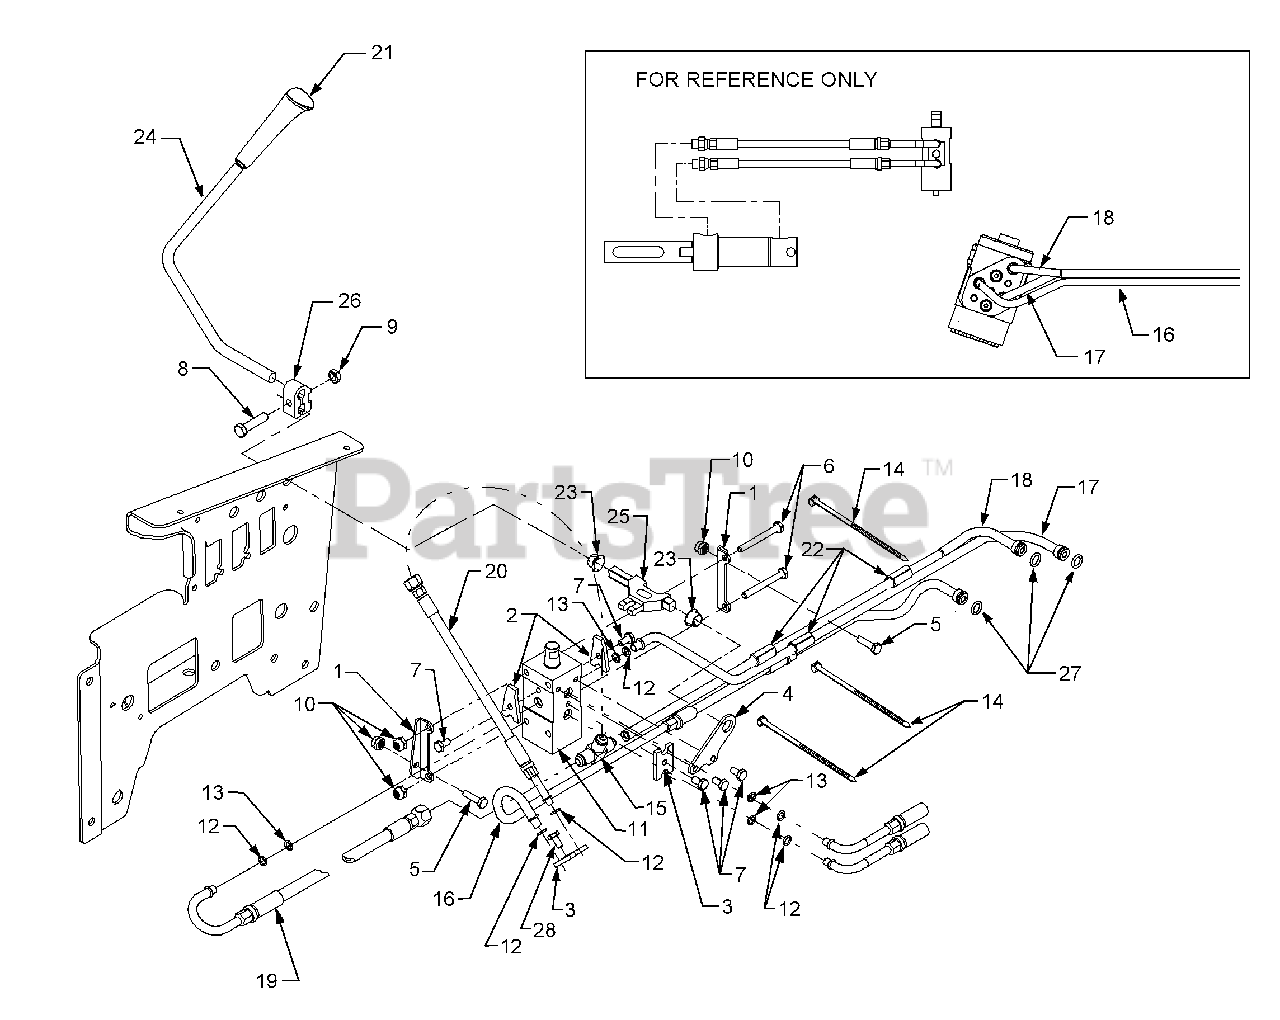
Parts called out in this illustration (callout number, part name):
1	Bracket, Valve Mounting
2	Clamp, Side Valve
3	Clamp, Double Valve
5	Screw, Hex Cap 1/4-20 x 1.0 GR5
6	Screw, Hex Cap 1/4-20 x 2.25 GR5
7	Screw, Hex Cap 1/4-20 x .50 GR5
8	Screw, Hex Cap 5/16-18 x 1.375 GR5
9	Nut, Hex Insert Lock, 5/16-18
10	Nut, Hex Flange Lock, 1/4-20
11	Valve, Hydraulic
12	O-Ring, Backup
13	O-Ring
14	Cable Tie
15	T-Fitting, 9/16-18 Thrd.
16	Tube, Hydraulic (Pump to Strng)
17	Tube, Hydraulic (Aux. from Strng)
18	Tube, Hydraulic (Strng Return)
19	Tube, Hydraulic (Aux Return)
20	Tube, Hydraulic (Return to Pump)
21	Knob, Lift
22	Rubber Spacer
23	Bearing, Nylon Flange
24	Handle, Center Lift Valve
25	Link, Lift
26	Clamp, Handle
27	O-Ring, .426 x .566 x .070
28	Screw, Hex Cap 1/4-20 x .62 GR5
